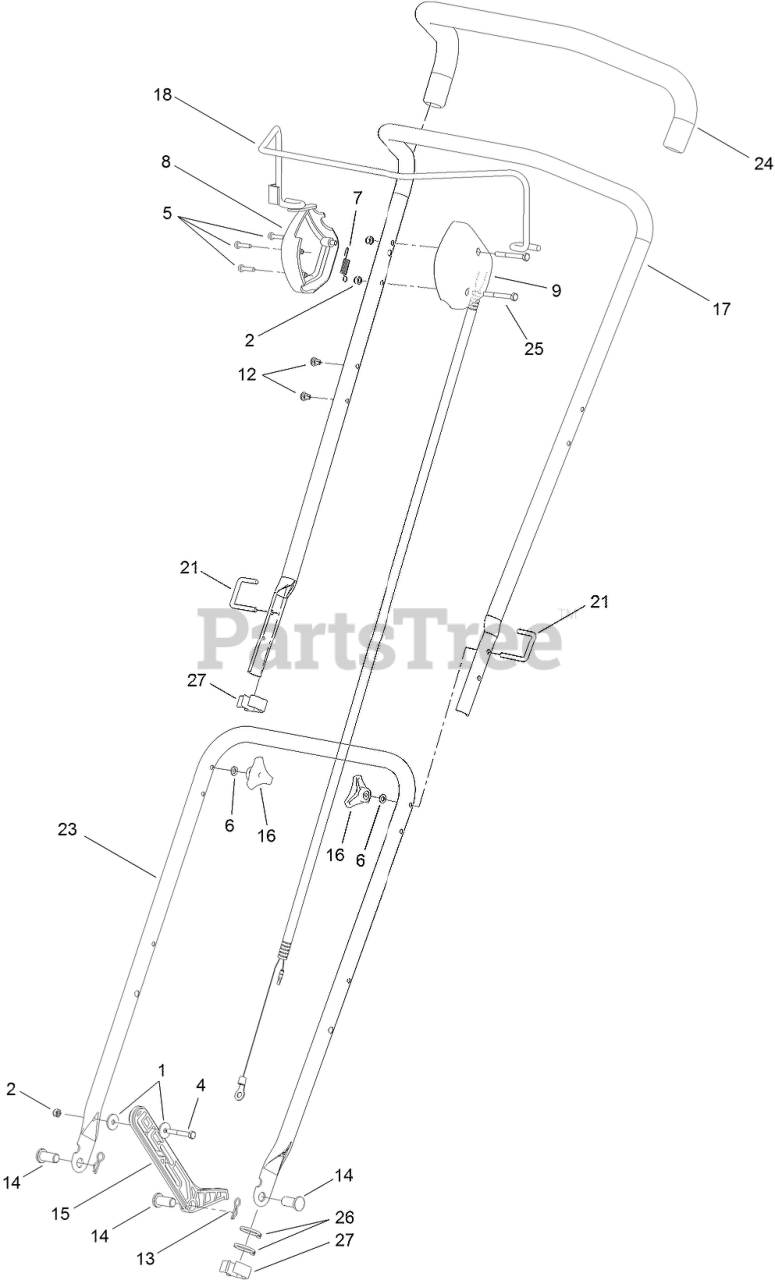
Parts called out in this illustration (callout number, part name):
1	WASHER
2	NUT-NYLOC
4	BOLT-HH
5	SCREW-PLASTITE
6	WASHER
7	SPRING-RETURN
8	BOX-SWITCH, LH
9	OPC WIRE LOOM ASM
12	FASTENER-DRIVE
13	CLIP-R
14	PIN-RETAINING
15	FOOTSTOP
16	HANDWHEEL
17	HANDLE-UPPER
18	ARM-BAIL
21	BOLT-U
23	HANDLE-LOWER
24	GRIP-HANDLE
25	BOLT-HEX
26	TIE-CABLE
27	GUIDE-CABLE
